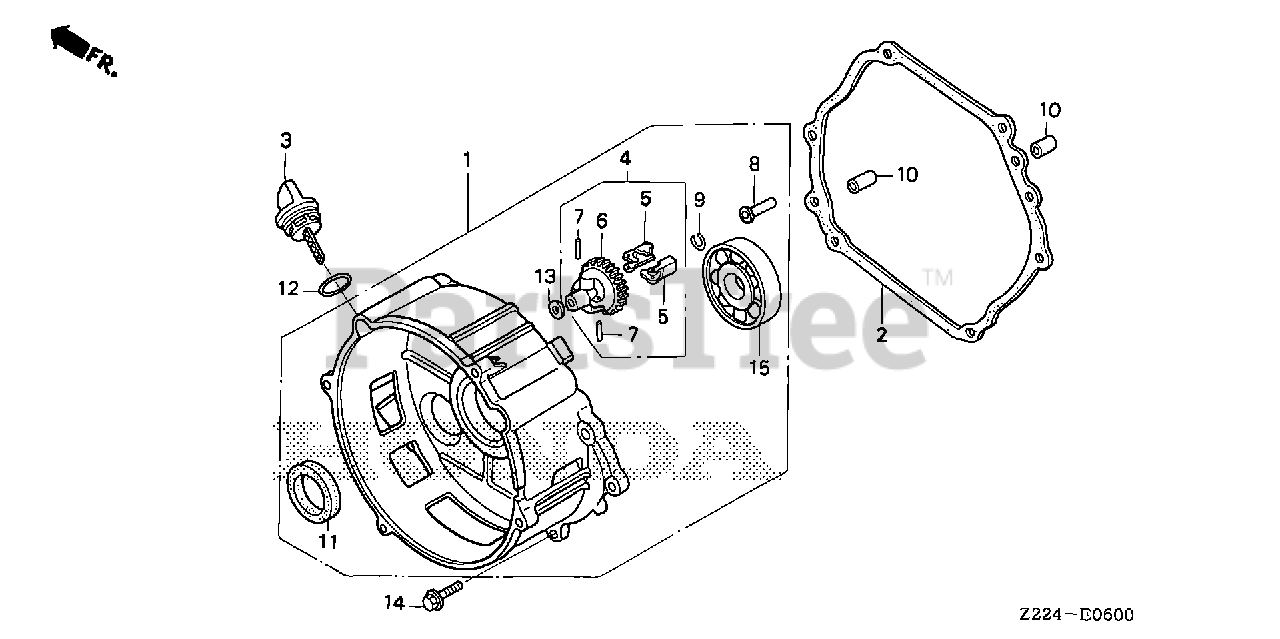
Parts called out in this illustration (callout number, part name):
1	COVER ASSY., CRANKCASE
2	GASKET, CASE COVER
3	CAP, OIL FILLER
4	GOVERNOR ASSY. (STD)
5	WEIGHT, GOVERNOR
6	HOLDER, GOVERNOR WEIGHT
7	PIN, GOVERNOR WEIGHT
8	SLIDER, GOVERNOR
9	CLIP, GOVERNOR HOLDER
10	PIN, DOWEL (8X12)
11	OIL SEAL (30X46X8)
12	O-RING (26X2.7)
13	WASHER, PLAIN (6MM)
14	BOLT, FLANGE (8X35)
15	BEARING, RADIAL BALL (6206)
